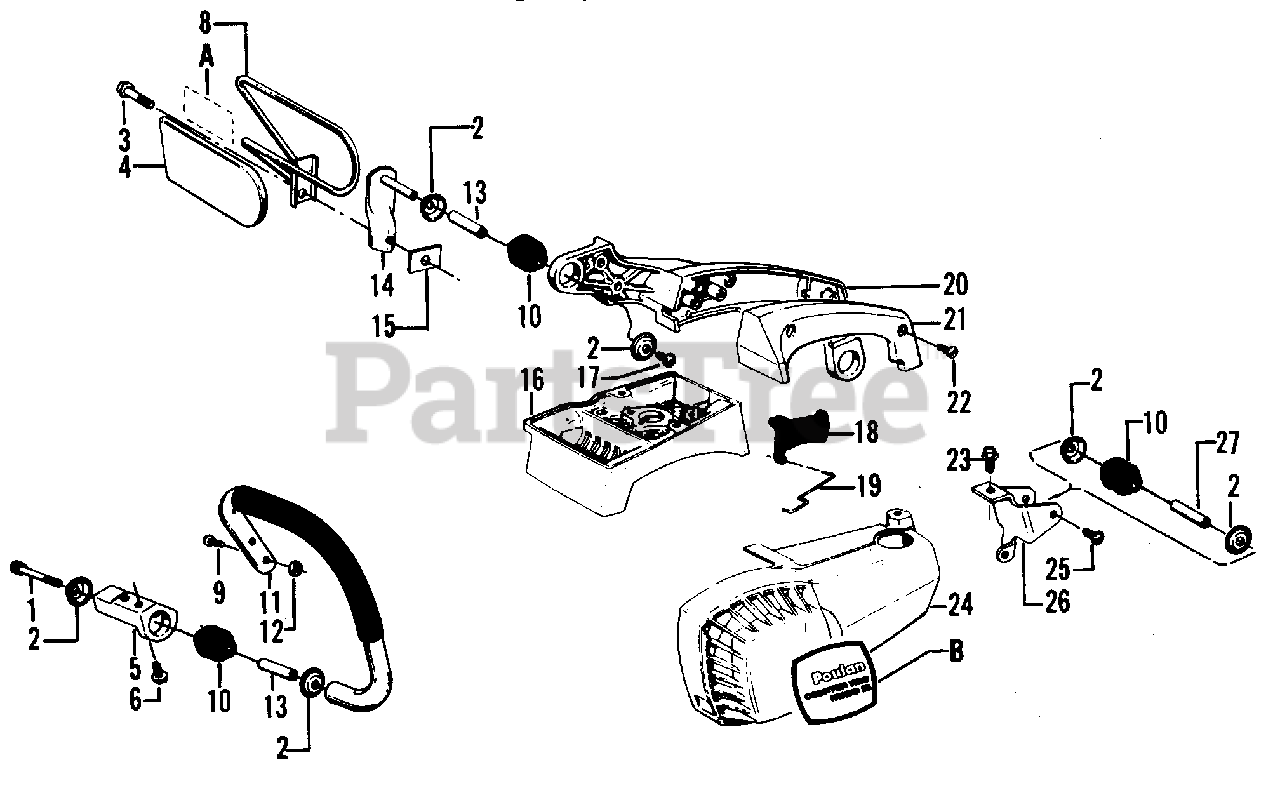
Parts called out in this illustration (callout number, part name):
1	Screw 1/4-20x1-3/4 Hex Socket Head
2	Cup-Isolator - See Service Reference 1
3	Screw 1/4-20x1-1/8 Hex Head
4	Sleeve-Handguard
5	Bracket-Isolator Mtg.
6	Screw 10-24x5/8 Hex Washer Head
8	Handguard (Inc. #4)
9	Screw 10-32x1-1/4 Socket Head
10	Isolator
11	Handlebar Assy.
12	Locknut-#10-32 Hex
13	Spacer-Isolator
14	Front Bracket & Spindle Assy.
15	Pad-Isolator
16	Carburetor Housing
17	Screw-8-32x9/16 Pan Hd. Taptite
18	Trigger-Throttle
19	Wire-Throttle
20	Rear Handle
21	Cover-Rear Handle
22	Screw-#8-32x9/16 Pan Hd. Taptite
23	Screw-1/4-20x1/2 Hex Cap
24	Fan Housing
25	Screw 8-32x7/16 Pan Head
26	Bracket-Isolator Mtg. Rear
27	Spacer-Rear Isolator
A	Decal-Kickback Warning
B	Decal-Fan Housing
